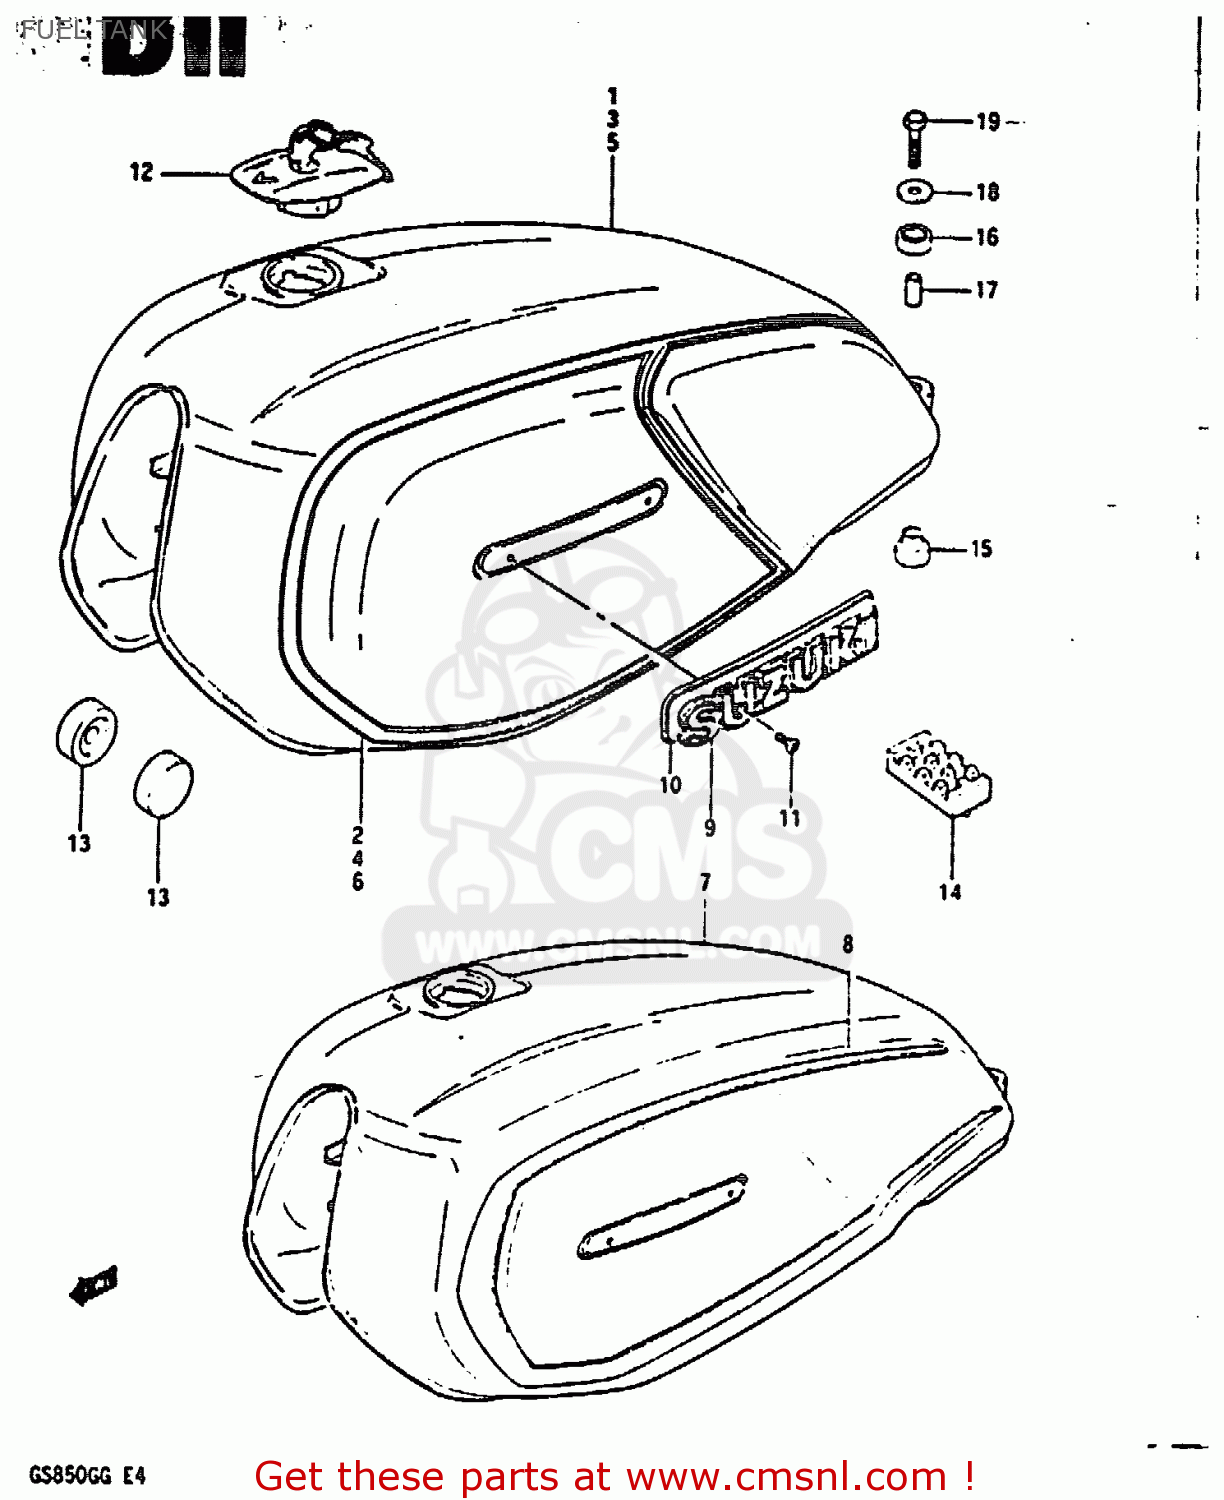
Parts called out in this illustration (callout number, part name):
1	TANK, FUEL
2	TAPE SET, FUEL TANK
3	TANK, FUEL
4	TAPE SET, FUEL TANK
5	TANK ASSY, FUEL (BLACK)
6	TAPE SET, FUEL TANK
7	TANK, FUEL
8	TAPE SET
9	EMBLEM,FUEL TANK
10	CUSHION, EMBLEM
11	SCREW 3X6
12	CAP SET,FUEL TANK
13	CUSHION
14	CUSHION,FUEL TANK
15	CUSHION
16	CUSHION
17	SPACER (6.4X9X21.5)
18	WASHER (6.5X24X1.6)
19	BOLT
